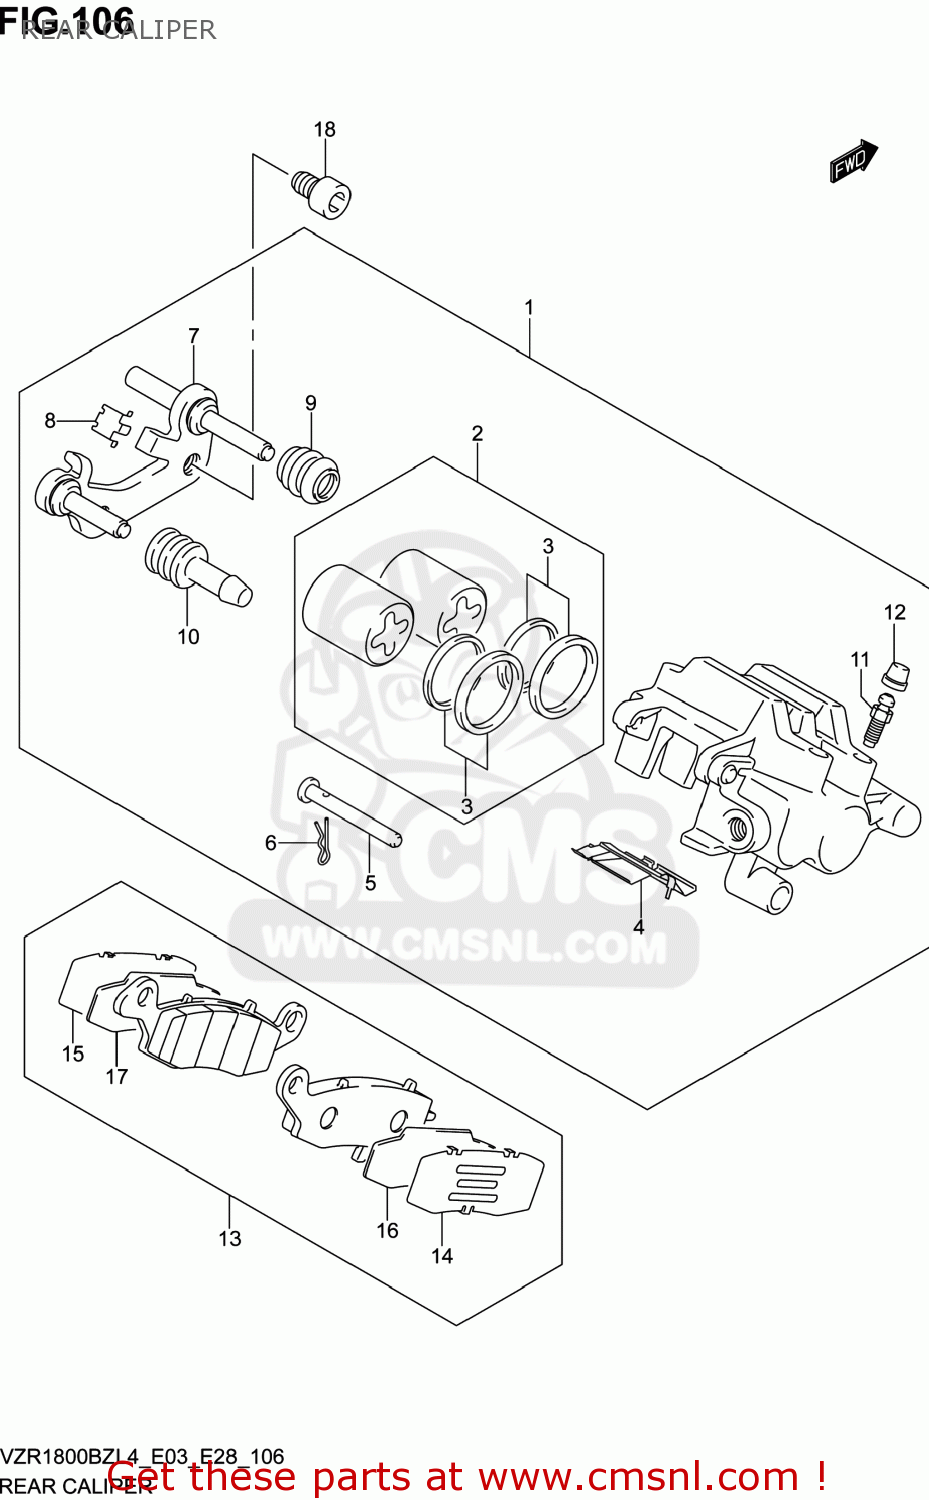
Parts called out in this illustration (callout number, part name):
1	CALIPER ASSY,RR
2	PISTON SET
3	SEAL SET,PISTON
4	SPRING,PAD
5	PIN,PAD
6	CLIP,PAD PIN
7	CARRIER,CALIPER
8	GUIDE,PAD
9	BOOT,AXLE
10	INSULATOR,AXLE
11	BLEEDER
12	CAP,BLEEDER PLUG
13	PAD & SHIM SET (NAS)
14	SHIM,PAD
15	SHIM,PAD NO.2
16	INSULATOR NO.1
17	INSULATOR NO.2
18	BOLT(10X20)
